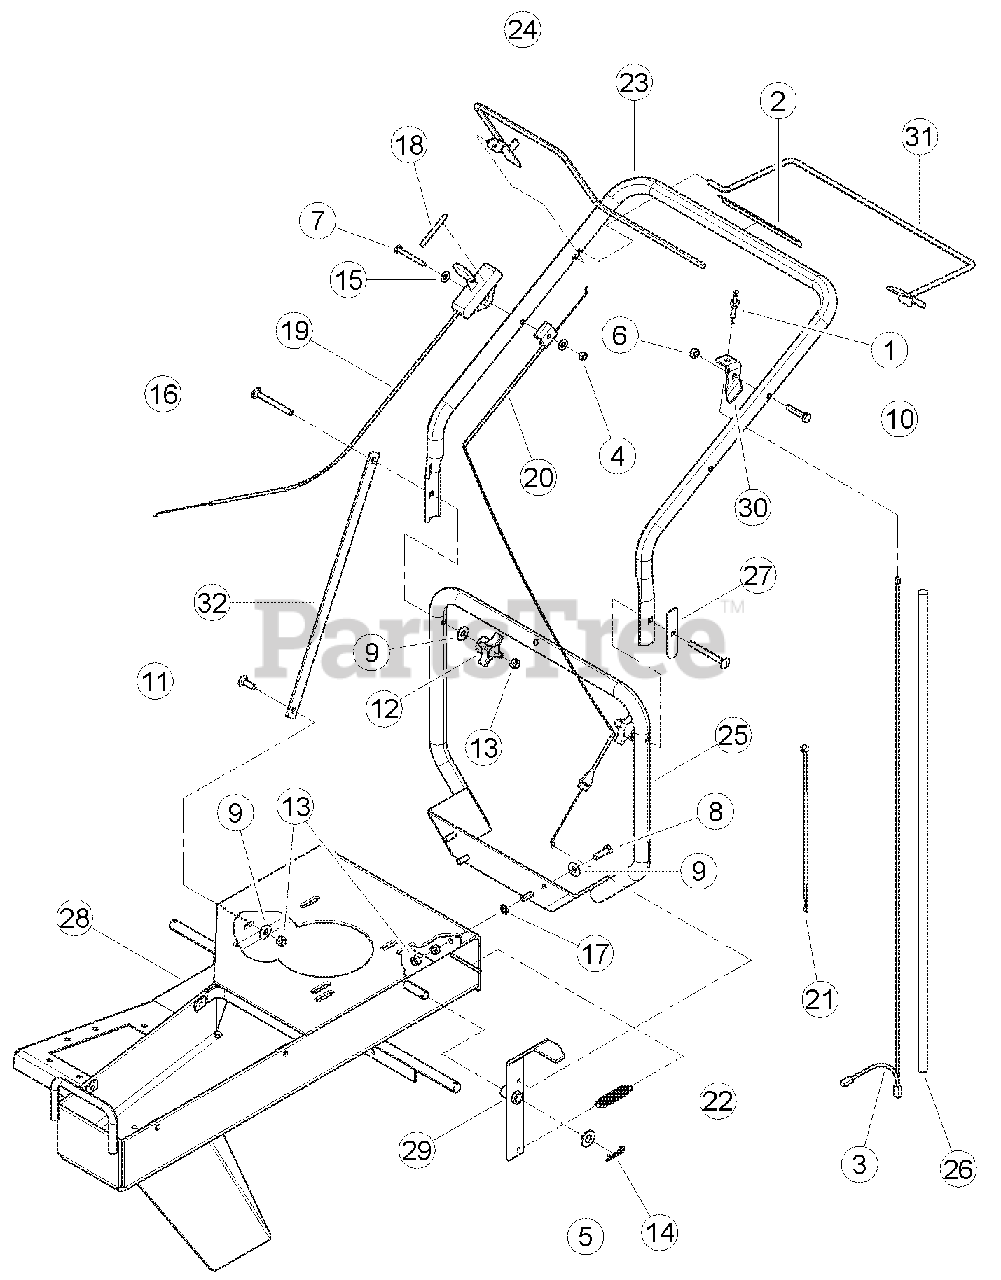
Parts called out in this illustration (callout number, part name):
1	SWITCH, ENGINE KILL
2	DECAL, STUMPGRINDER CONTROL
3	WIRE ASSY, ENGINE KILL
4	NUT, 1/4 CENTERLOCK NC ZP
5	WASHER, 1/2 SAE FLAT ZP
6	NUT, 5/16 CENTERLOCK NC ZP
7	BOLT, 1/4 X 2-1/4 HCS GR5 ZP
8	BOLT, 5/16 X 1 HHCS GR5 NC ZP
9	WASHER, 5/16 FLAT ZP
10	BOLT, 5/16 X 1-1/2 HEX HD GR5 ZP
11	BOLT, 5/16 X 1 CRG GR5 ZP
12	KNOB, SPOUT 5/16-18
13	NUT, 5/16 NE NYLOCK ZP
14	HAIRPIN CLIP ZP #203
15	WASHER, 5/16 SAE FLAT ZP
16	BOLT, 5/16 X 3 CRG GR5 NC ZP
17	WASHER, 5/16 EXTERNAL TOOTH ZP
18	DECAL, THROTTLE
19	THROTTLE CONTROL
20	CABLE, STUMP GRINDER
21	STRAP, 11 IN. BLACK TIE
22	SPRING, LT EXT .555OD X 2.75LG
23	UPPER HANDLE BAR
24	TOP BALE WELDMENT
25	WELDMENT, HANDLEBAR
26	CONDUIT, 1/4 X 47 WIRE
27	BRACE, HANDLEBAR
28	WELDMENT, STUMPGRINDER FRAME
29	WELDMENT, WHEEL BRAKE
30	STRIP, SWITCH MOUNT
31	WELDMENT, BOTTOM BALE
32	STRIP, HANDLEBAR SUPPORT
